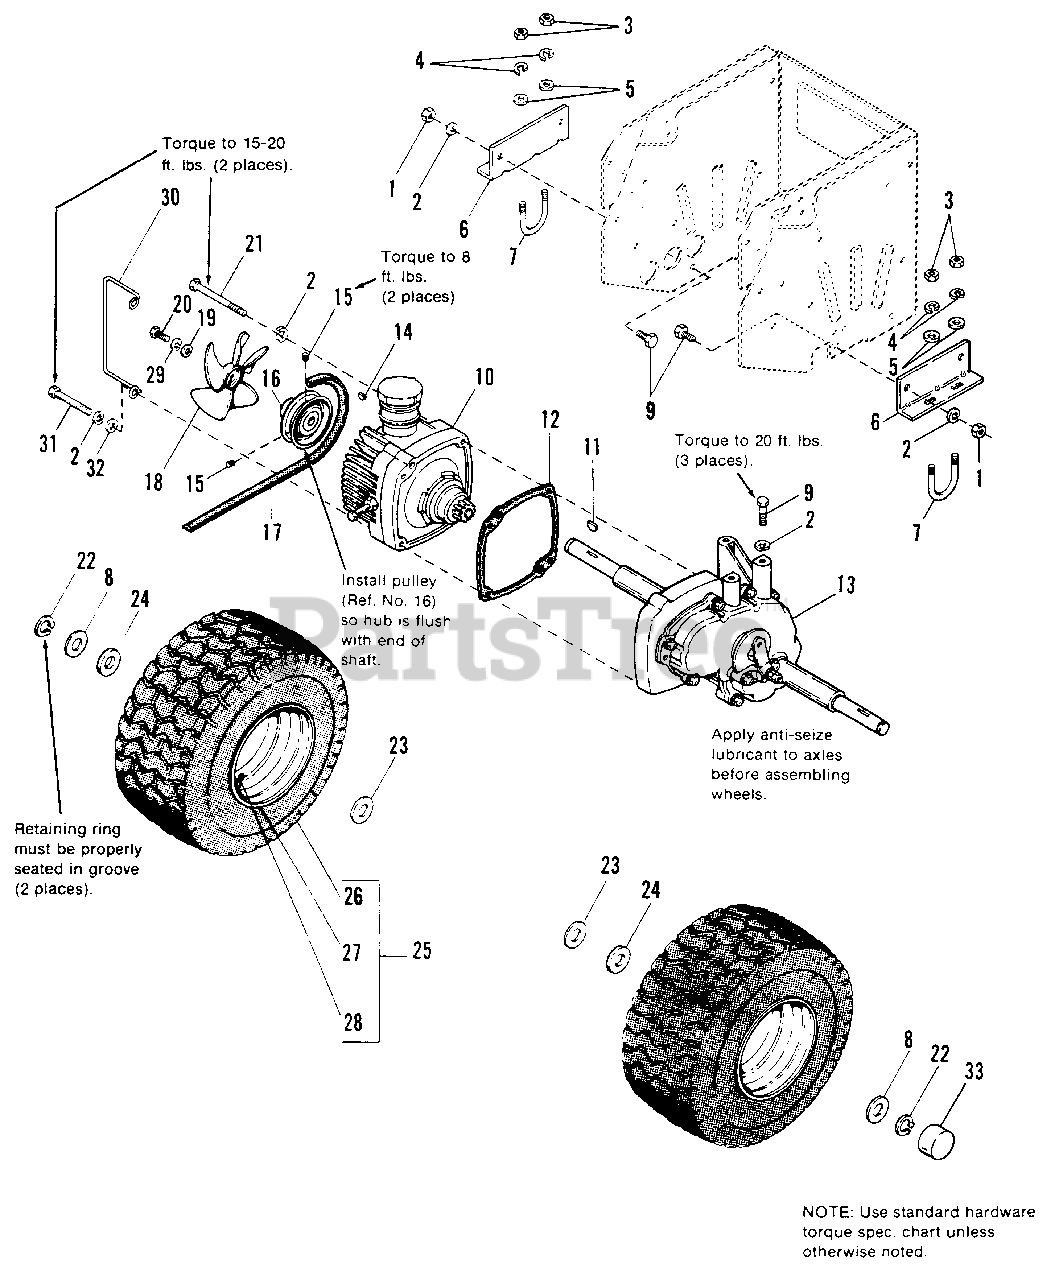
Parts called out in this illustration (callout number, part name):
1	NUT, Hex, 3/8-16
2	LOCKWASHER, 3/8
3	NUT, Hex, 5/16-18
4	LOCKWASHER, 5/16
5	WASHER, 5/16
6	SUPPORT, Transmission
7	"U" BOLT, Axle
9	CAPSCREW, Hex, 3/8-16 x 1
10	TRANSMISSION, Hydrostatic (See pages 22 & 23 for service parts.)
11	KEY, Woodruff, #18, 1/4 x 1-1/4
13	GEAR REDUCTION & DIFFERENTIAL ASSY. (See pages 48-51 for parts lists.)
14	KEY, Woodruff, #3, 1/8 x 1/2
15	SETSCREW, Sq. Hd., 1/4-28x 1/2
16	PULLEY, Transmission
17	BELT, "V" Drive
18	FAN, 7" Diameter
19	WASHER, 1/4 x 1-1/4 x 14 Ga.
20	CAPSCREW, Hex, 1/4-2 x 1/2
21	CAPSCREW, Hex, 3/8-16 x 3
22	RING, Retainer
24	WASHER, Plain, 1-1/32 x 1-3/4 x 3/16
25	WHEEL & TIRE ASSY. 18 x 8.50-8 (1690995, 1691029)
25	WHEEL & TIRE ASSY. 18 x 8.50-8, Turf Mate (1691271 & 1691325)
26	TIRE, 18 x 8.50-8 (Carlisle)(1690995, 1691029)
26	TIRE, 18 x 8.50-8 (Carlisle)(1691271, 1691325) Turf Mate
28	VALVE STEM & CAP
29	LOCKWASHER, 1/4
30	STOP, Drive Belt
31	CAPSCREW, Hex, 3/8-16 x 3-1/4, Gr. 5
32	WASHER, 3/8 Std.
33	CAP, Hub, Threaded
